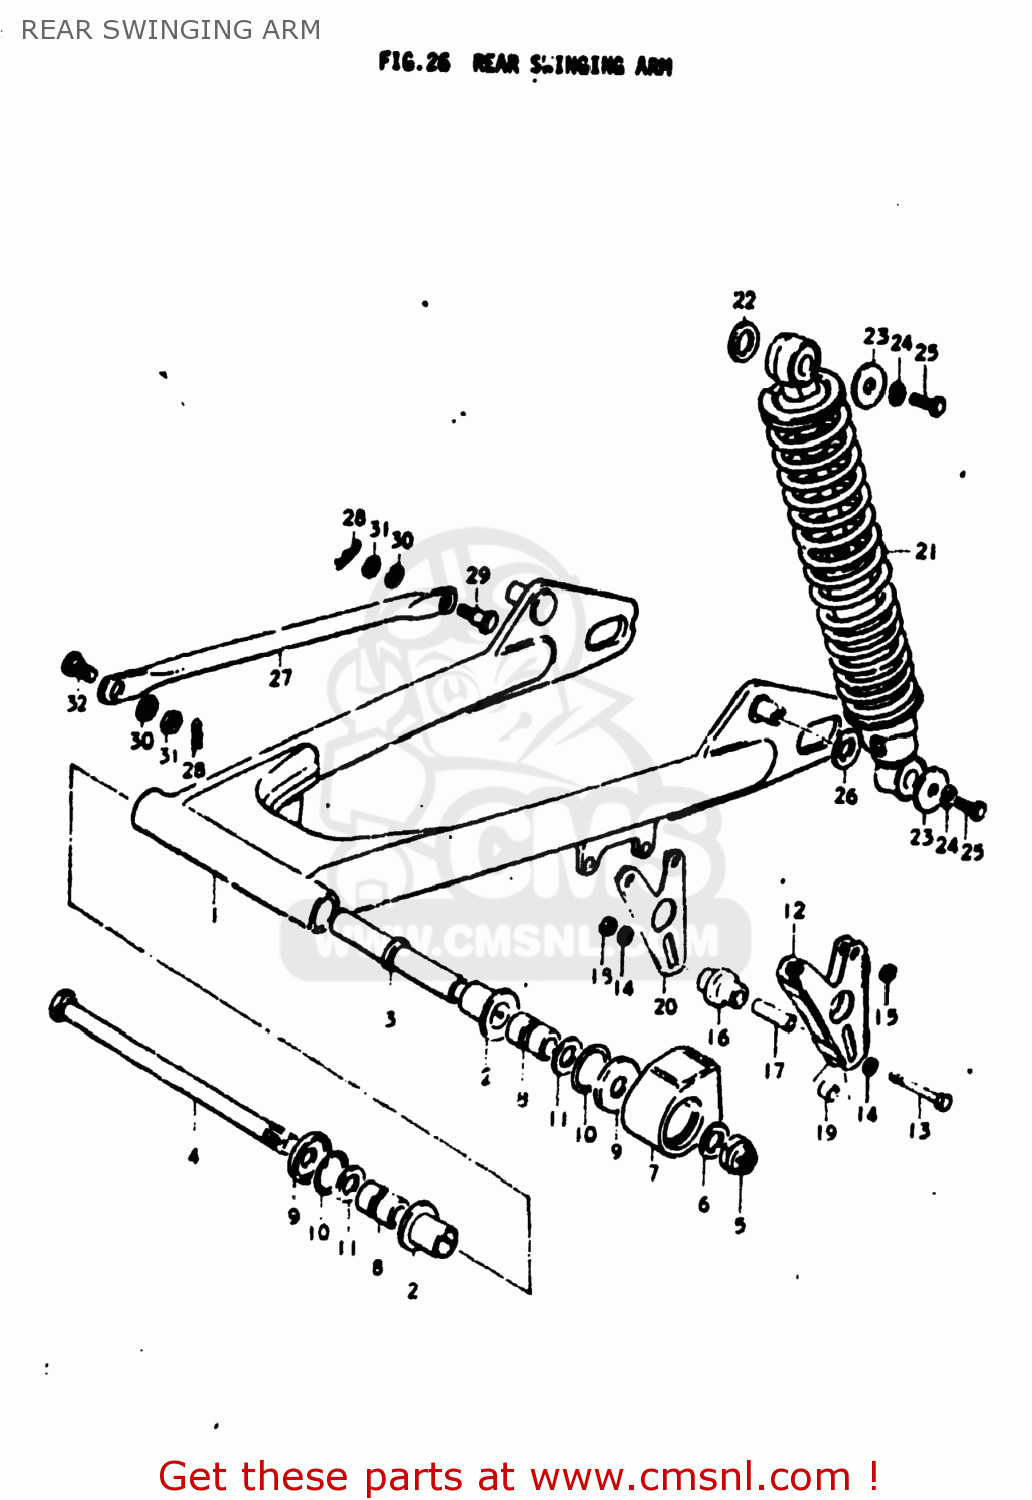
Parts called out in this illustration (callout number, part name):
1	SWING ARM ASSEMBLY,REAR
2	BUSHING
3	SHAFT,REAR SWING ARM
4	NUT
5	WASHER
6	SPACER,RR SWGARM PIVOT
7	COVER,SWGARM BUSH DUST SEAL
8	O RING(D:2,ID:24.5)
9	WASHER(12.5X24X2.3)
10	SPACER,SWING ARM,CENTER
11	BUFFER,CHAIN TOUCH DEFENSE
13	BOLT
14	LOCK WASHER
15	SPACER(6.5X12X6.9)
16	ROLLER,CHAIN GUIDE
17	NUT (6MM)
18	SPACER(6.3X9.3X16.5)
19	TENSIONER,CHAIN
20	WASHER
21	ABSORBER ASSEMBLY,REAR SHOCK
22	BOLT 12X50
23	BOLT(12X33)
24	WASHER
25	TORQUE LINK,REAR
26	CLIP
27	BOLT(8X26.5)
28	LOCK WASHER
29	NUT
30	BOLT(8X22)
